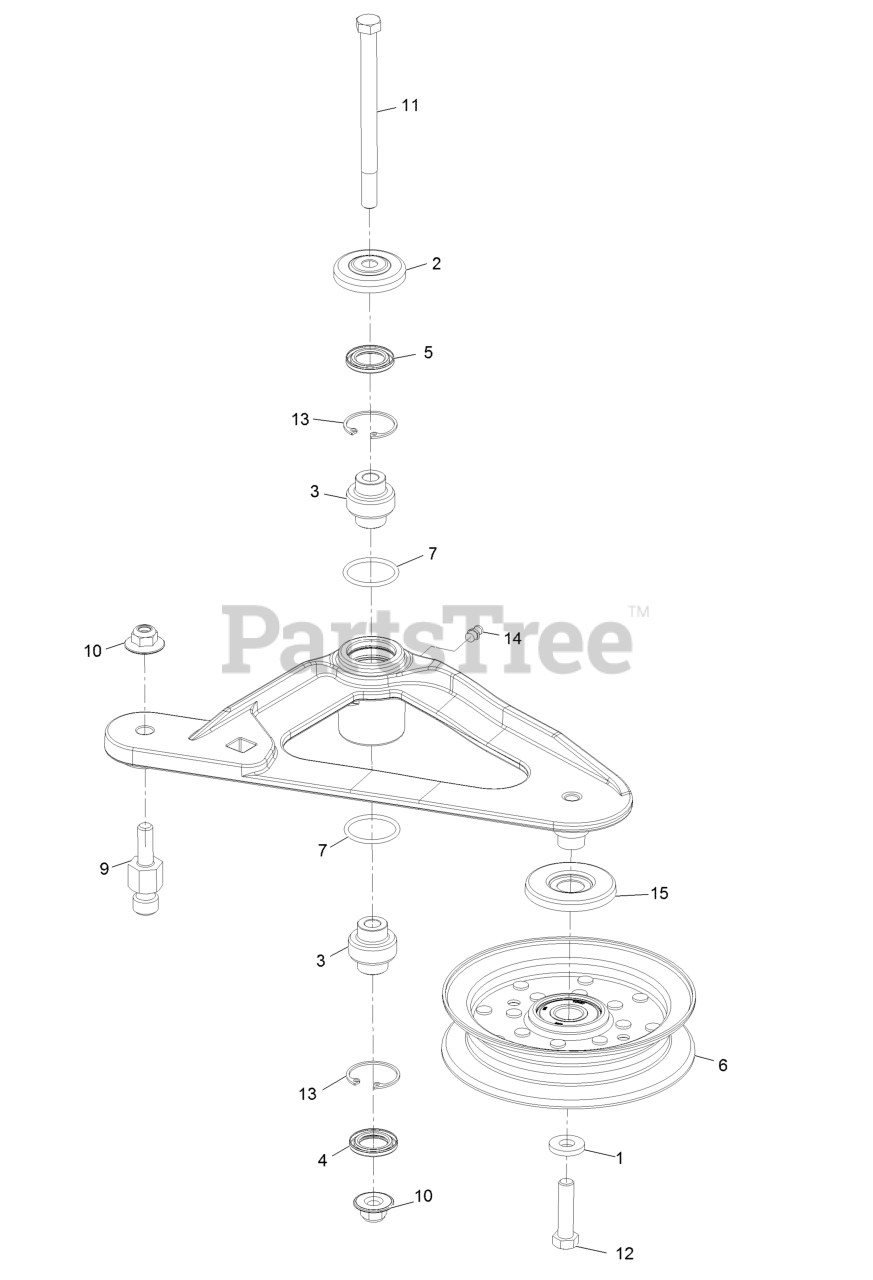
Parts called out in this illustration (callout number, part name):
2	Guard-Top
3	Bearing-Spherical
4	Seal-Lip, Double
5	Seal-Lip, Single
6	Idler-Pulley, Flat
9	Pin-Spring, Anchor
10	Nut-Flange, NI
11	Screw-Shoulder, HH
12	Screw-HH
13	Ring-Snap
14	Fitting-Grease
15	Shield-Guard, Dust
